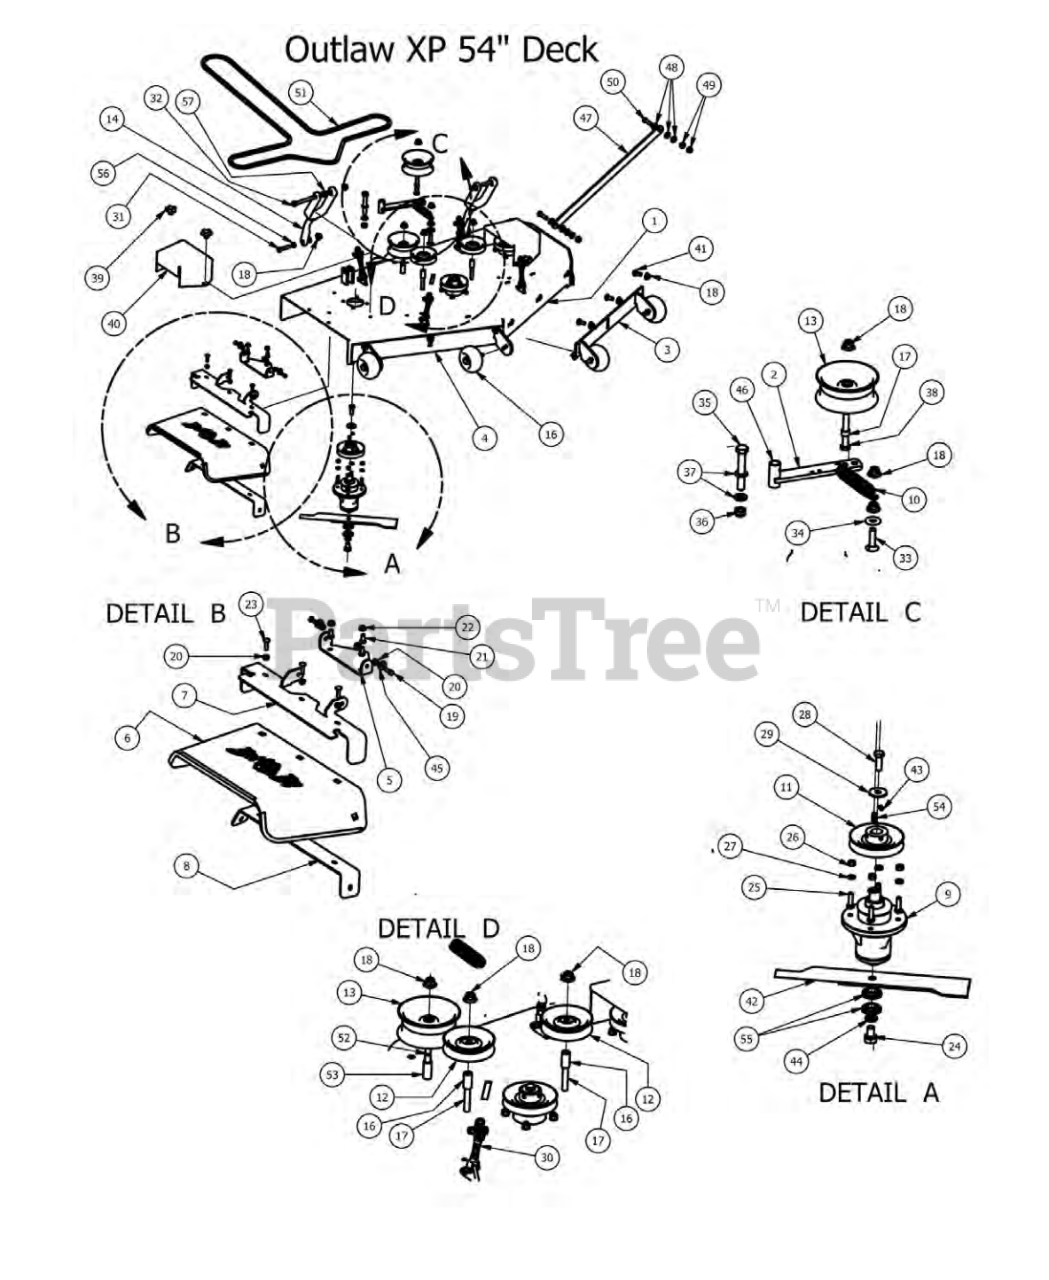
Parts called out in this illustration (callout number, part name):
1	54" Outlaw Deck
2	Deck Idler Bracket
3	54 Outlaw Adjustable Deck Front (Right)
4	54 Outlaw Adjustable Deck Front (left)
5	Discharge Chute Hanger (deck mounted)
6	Rubber Discharge Chute
7	Dischurge Chute Upper Hanger
8	60" Lower Hanger
9	Double Bearing Spindle Assembly
10	2009 Deck/Pump Idler Spring
11	5" Deck Pulley
12	43/4" Idler Pulley
13	Idler Pulley
14	Deck Hanger
15	Deck Wheel
16	Pulley Spacer
17	1/2 x 3 1/2 Flange Bolt Grade 8
18	3/4 OD x 1/2 ID x 3\4 Length
19	5/16" x 1" Bolt
20	5/16" Flange Nut
21	3/8" x 3/4" Hex Bolt
22	3/8" Flange Nut
23	5/16" x 1 1/4" Carriage Bolt
24	5/8" x 1 1/2" Grade 8 Bolt
25	3/8" x 1 1/4" Hex Bolt
26	3/8-16 Hex Nuts Zinc
27	3/8" Lock Washer
28	1/2"-20 x 1 1/2 Grade 5 Fine Thread Bolt
29	1/2 Belleville Washer
30	3-Link Adjustable Deck Hange
31	1/2-13X 2-1/4 GR Hex Bolts
32	1/2" x 5 1/2" Bolt
33	1/2 x 2" Carriage Bolt
34	1/2" Flat Washer
35	5/8" x 4" Hex Bolt
36	5/8" Nylock (1/2 Jam)
37	.635 ID Plastic Washer
38	Spacer 3/4 OD x 1/2 ID x 75
39	5/16" Knob
40	Pulley Cover
41	1/2" x 1 1/4 Carriage Boit
42	54" Deck Fusion Blade For Outlaw
43	3/8" Set Screw
44	5/8" Lock Washer
45	360 ID Plastic Washer
46	Deck Idler Assembly Componets13,18,17,38,2
47	Outlaw Panhard Link
48	505 Nylon Spacer
49	1/2" Flange Nut
50	1/2-13x2 GR 5 Hex Bolt
51	B165 Belt-60 54" deck Outlaw
52	1/2" x 4" Bolt (Grade 8)
53	1 3/4" Pulley Spacer
54	1/4" x 1" Key
55	Double Bearing For Spindle
56	Flange for Lower Deck Arm
57	Flange Bushing for Deck Arm Upper
